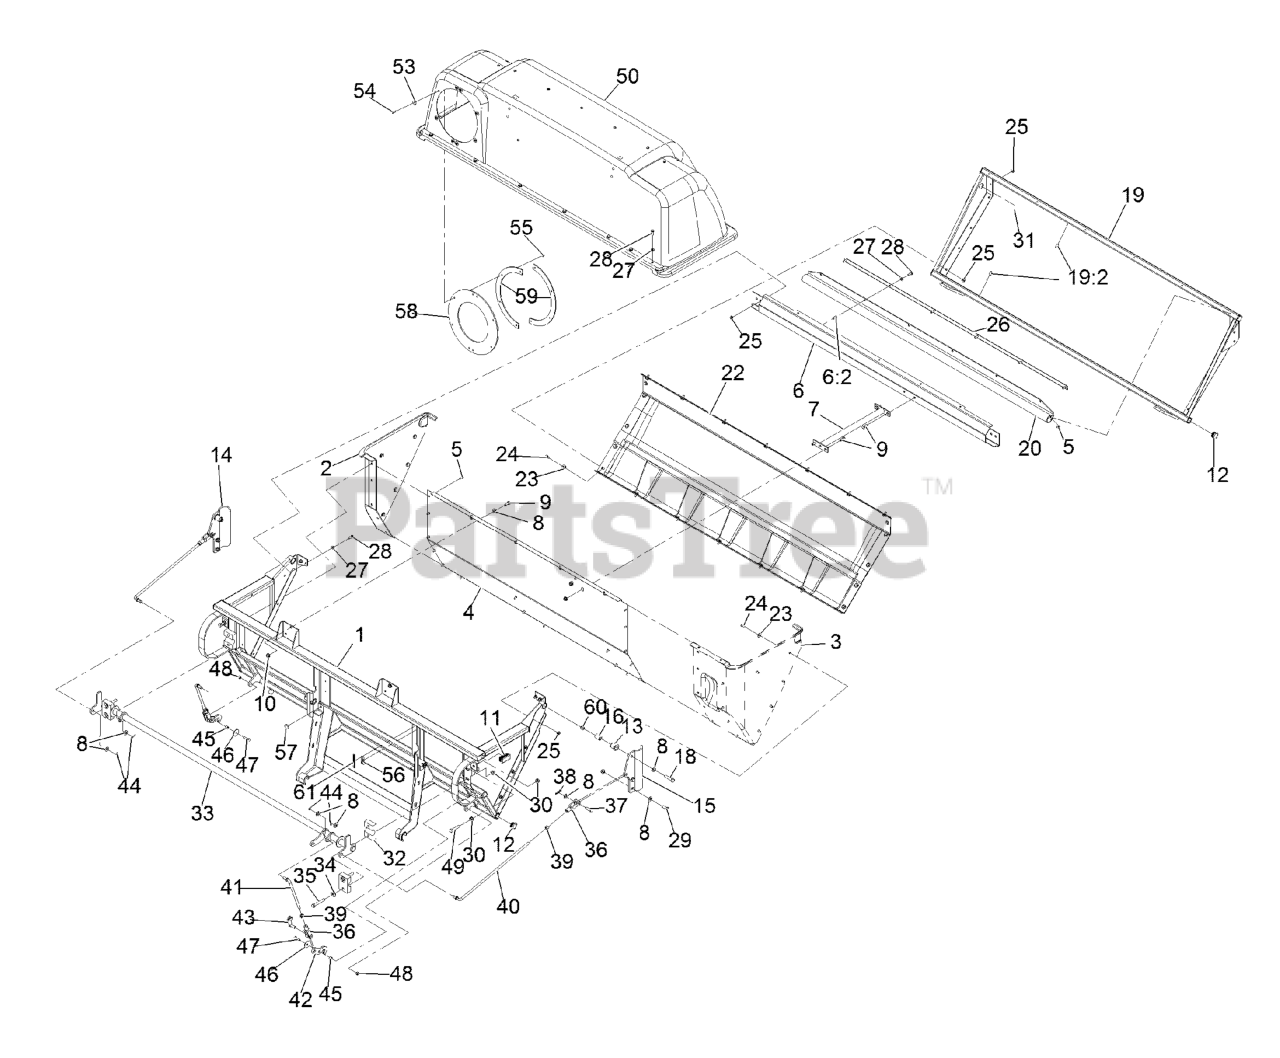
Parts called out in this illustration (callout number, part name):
2	PANEL-BAGGER, RH
3	PANEL-BAGGER, LH
4	SHEET-WALL
5	RIVET-BLIND
6	REAR CROSSMEMBER ASM
6:2	NUT-CLINCH
8	WASHER-FLAT
9	SCREW-HH
13	BUSHING
14	ARM-HINGE, RH
15	ARM-HINGE, LH
16	PIN-PIVOT, HINGE
18	SCREW-HH
19	DOOR ASM
19:2	NUT-CLINCH
20	SEAL-DOOR HINGE
22	BAG AND BOTTOM PANEL ASM
23	WASHER-FLAT
24	SCREW-HH
26	STRAP-HOLD DOWN
27	WASHER-FLAT
28	SCREW-HH
29	SCREW-HH
30	NUT-HHF, WHIZ
31	PLUG-DOME
33	LINK-INTERMEDIATE
34	WASHER-FLAT
35	SCREW-HH
36	YOKE-LINKAGE, BRAKE
37	PIN-CLEVIS
38	PIN-COTTER
39	NUT-HEX
40	LINK-HINGE
41	LINK-HANDLE
43	PIN-SPRING, CLEVIS
44	PIN-COTTER
46	WASHER-FLAT
47	SCREW-HH
48	NUT-LOCK, NI
49	SCREW-HH
50	ASM,HOOD DUMP
53	WASHER-FLAT
54	SCREW-PPH
55	NUT-LOCK, NI
56	Decal-Patent Ttco.Com
58	SEAL-TUBE
59	CLAMP-SEAL
60	NUT-LOCK, NI
61	DECAL-WARNING
